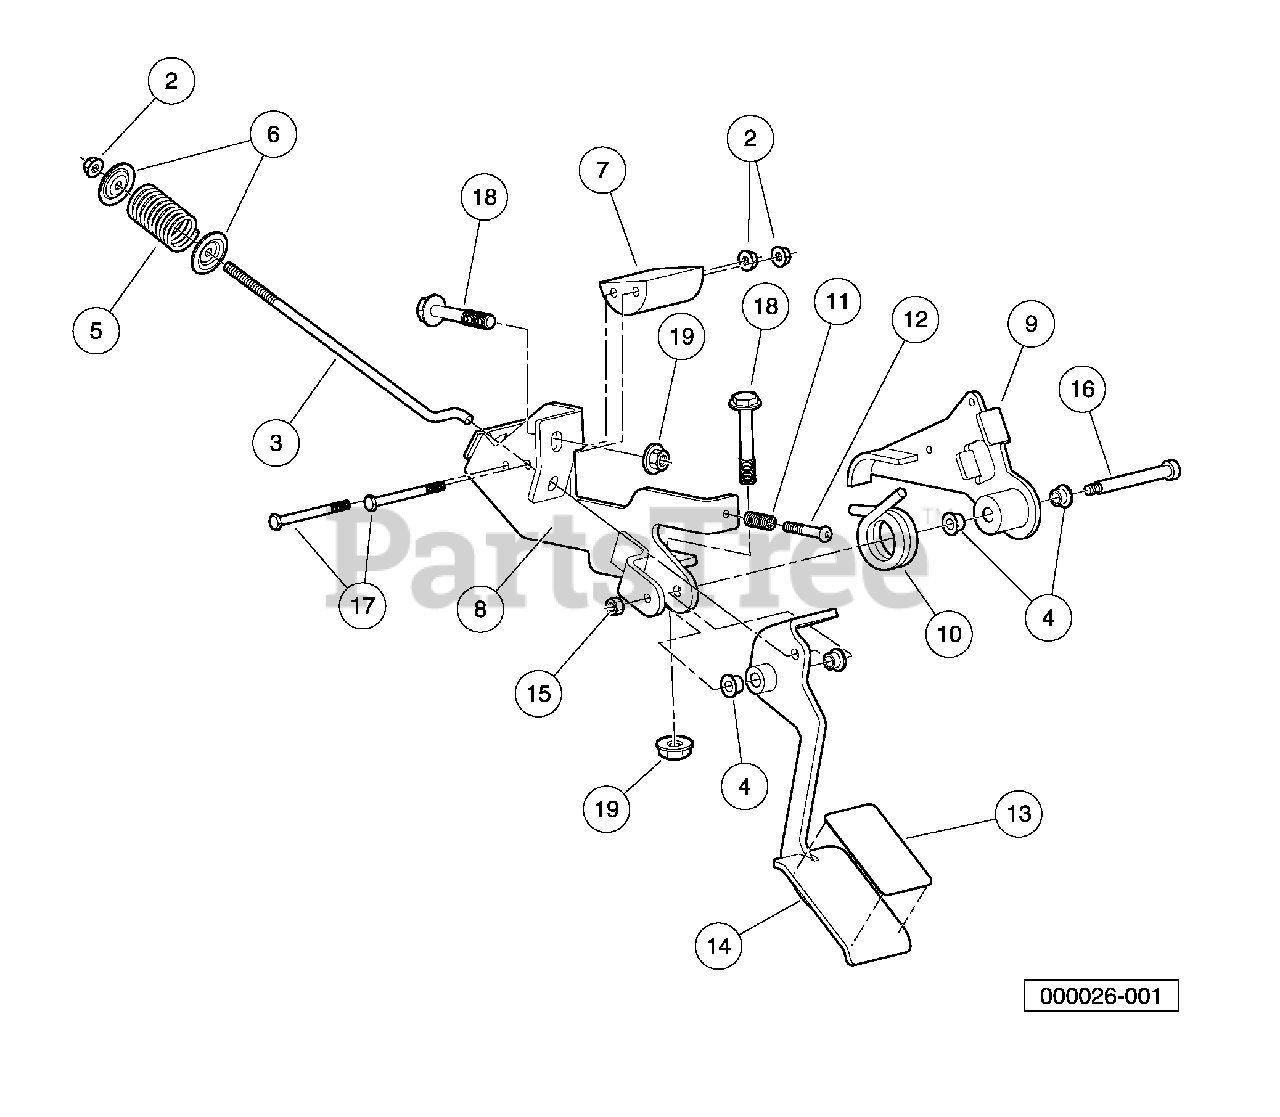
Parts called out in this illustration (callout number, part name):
1	Asm, Pedal, Accelerator
2	Nut-m6x1.0 Flng All Mtl Lock
3	Pullrod, Spring, Compression
4	Bushing, Greaseless
5	Spring, Comp, Pedal, Pullrod
7	Guide, Cable, Accelerator
8	Weldment, Bracket, Pedal
9	Weldment, Lever, Motion, Lost
10	Spring, Torsion
11	Spring, Stop, Pedal
12	Bolt, Stop, Pedal
13	Pad, Grip Tape, Accelerator
14	Weldment, Pedal, Accelerator
15	Nut M6x1 Mech Def Center
16	Bolt, Shoulder, M8 X 70, Hc
17	Bolt, M6 X 1 X 70
18	Bolt Flanged Head, M8 X 1.25 X 65
19	Lock Nut, Flg M8 X 1.25 Nylon
